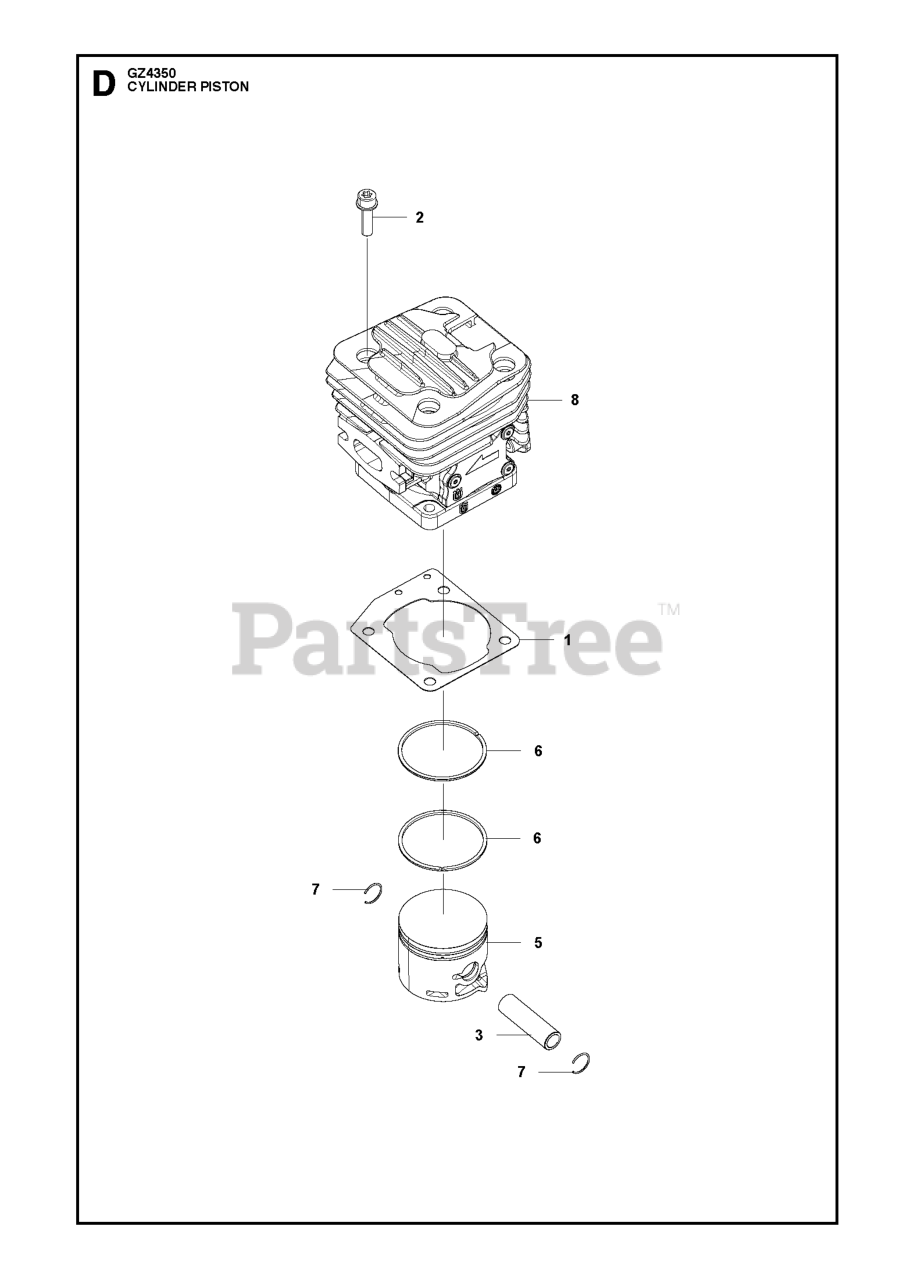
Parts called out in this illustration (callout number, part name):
2	BOLT 8488152020
6	PISTON RING T1.2 D42
8	CYLINDER ASSY
